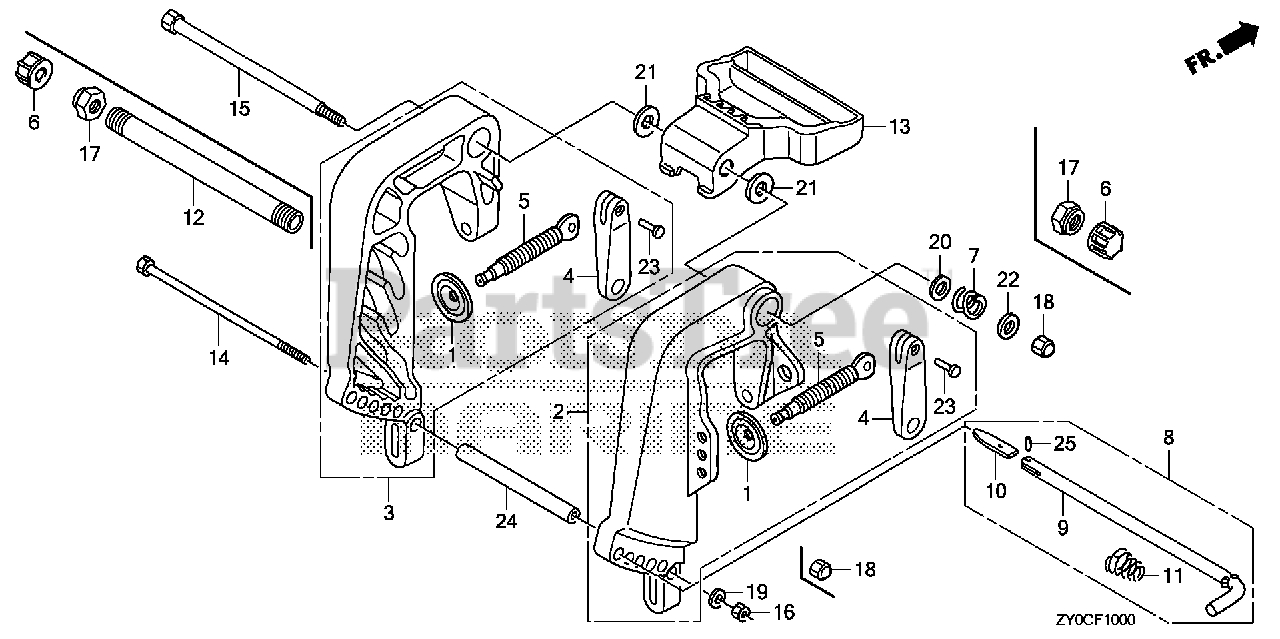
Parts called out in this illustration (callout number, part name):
1	PLATE, PUSH
2	BRACKET, R. STERN *NHB14M* (AQUA MARINE SILVER METALLIC)
3	BRACKET, L. STERN *NHB14M* (AQUA MARINE SILVER METALLIC)
4	GRIP, CLAMP
5	SCREW, CLAMP
6	CAP, TILTING BOLT
8	ROD, ADJUSTING
9	ROD, ADJUSTING
10	STOPPER, ROD
11	SPRING, ADJUSTING ROD
12	SHAFT, TILTING
13	HANDLE, CARRYING REMOTE
14	BOLT, HEX. (8X163)
17	NUT, SELF-LOCK (7/8-14UNF)
18	NUT, SELF-LOCK (8MM)
19	WASHER, PLAIN (8MM) Use up to Frame SN 4800712.
21	WASHER, WAVE (22MM)
23	RIVET (4X22.6)
24	COLLAR, DISTANCE (8MM)
25	PIN, SPRING (2.5X8)
